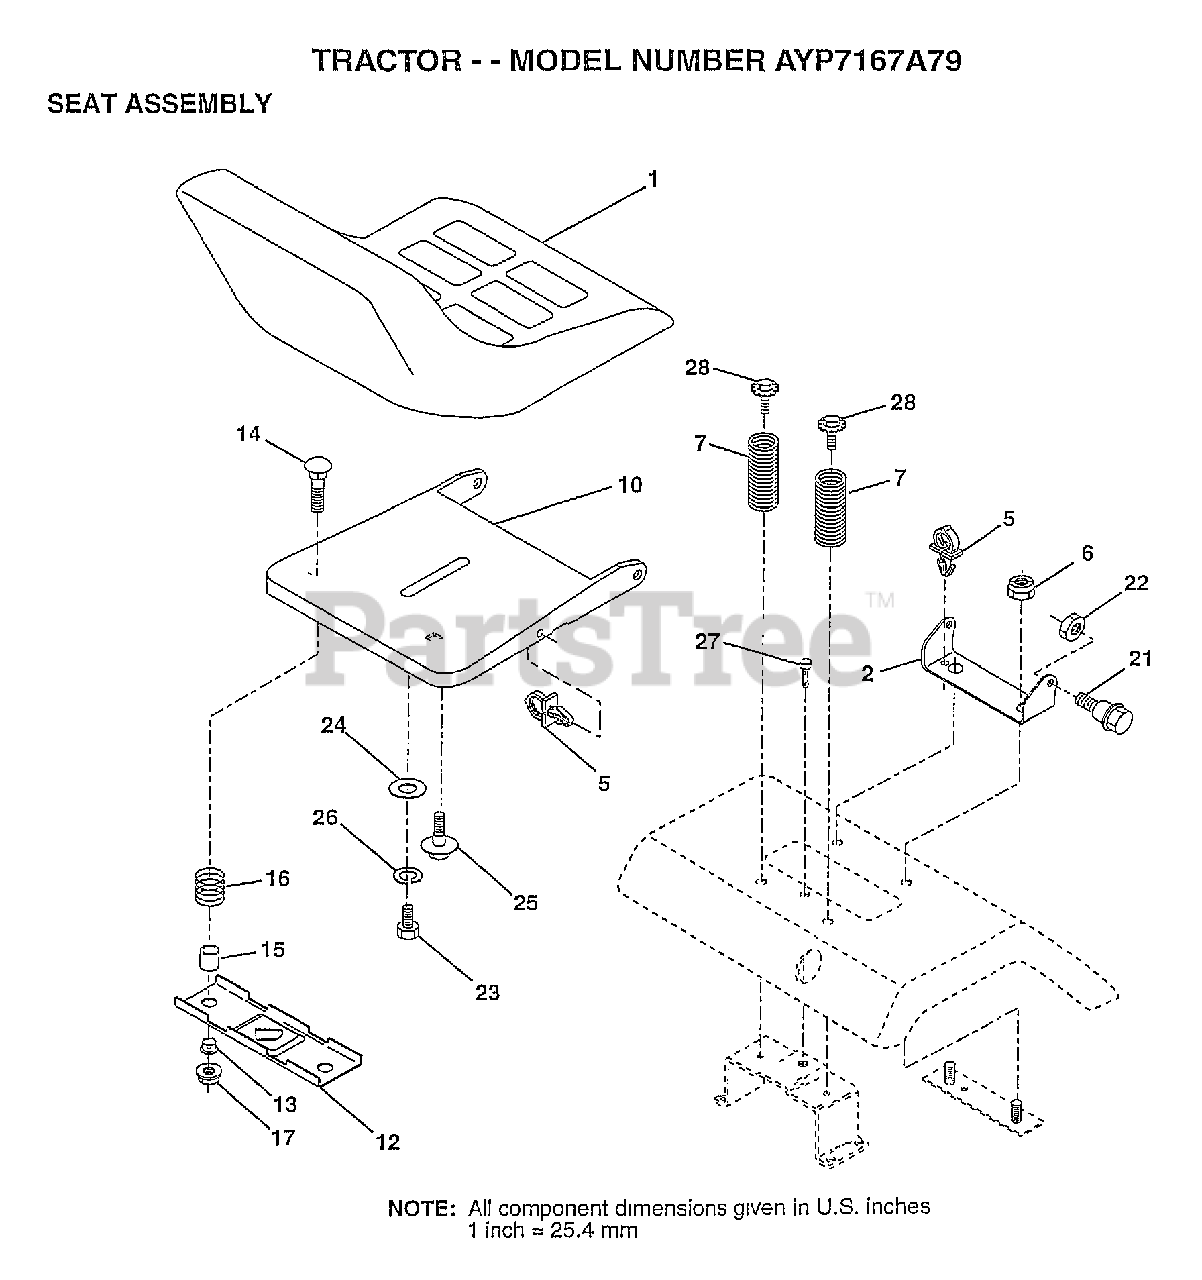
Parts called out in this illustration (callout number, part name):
1	SEAT
2	BRACKET PVT SEAT
5	CLIP.PUSH-IN.HING
6	NUT
7	SPRING COMPRESSIO
10	PAN-SEAT
12	BRKT SWITCH
13	BUSHING
15	SPLIT SPACER
16	SPRING
21	"BOLT,SHOULDER"
22	NUT
23	BOLT
24	WASHER
25	"BOLT,SHOULDER"
26	LOCKWASHER
27	SCREW LT
28	BOLT.5/16-18.UNC
